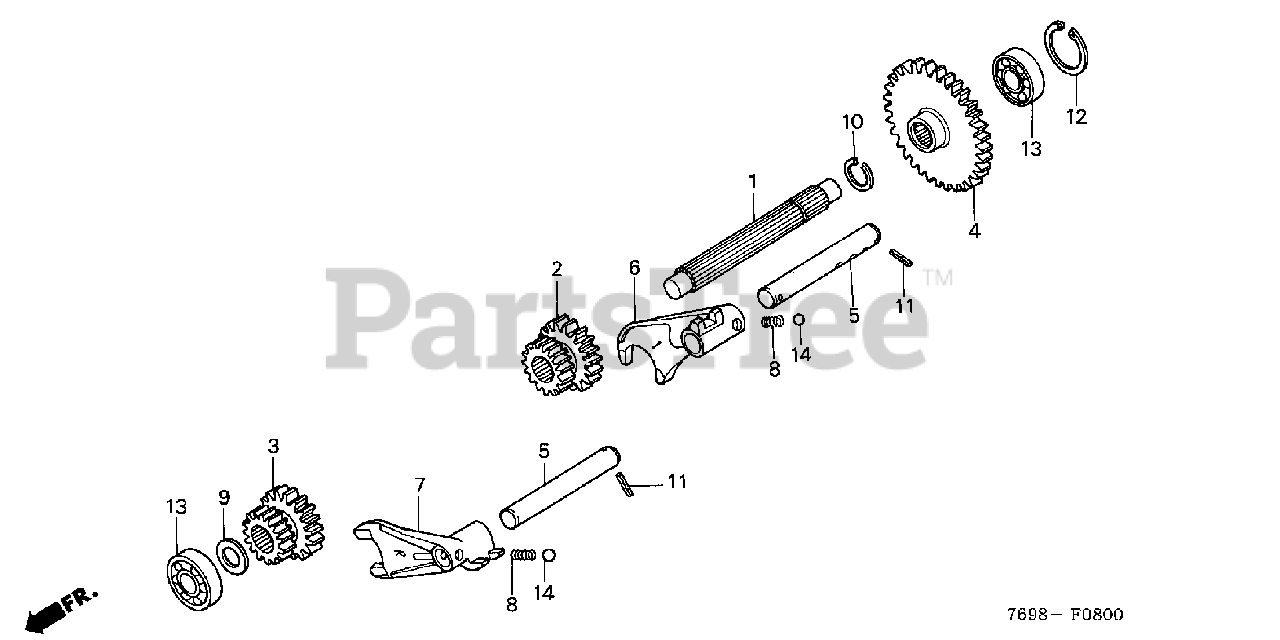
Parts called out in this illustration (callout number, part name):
1	COUNTERSHAFT (UPPER)
2	GEAR, FIRST-SECOND CHANGE (27T-17T)
3	GEAR, REVERSE CHANGE (27T-17T)
4	GEAR, COUNTERSHAFT (53T)
5	SHAFT, MAIN CHANGE
6	FORK, SHIFT (1-2)
7	FORK, REVERSE SHIFT
8	SPRING A, BALL SETTING
9	WASHER (17MM)
10	CIRCLIP (OUTER) (20MM)
11	PIN, SPRING (3X18)
12	CIRCLIP (INNER) (40MM)
13	BEARING, RADIAL BALL (6203)
14	BALL, STEEL (#10) (5/16)
